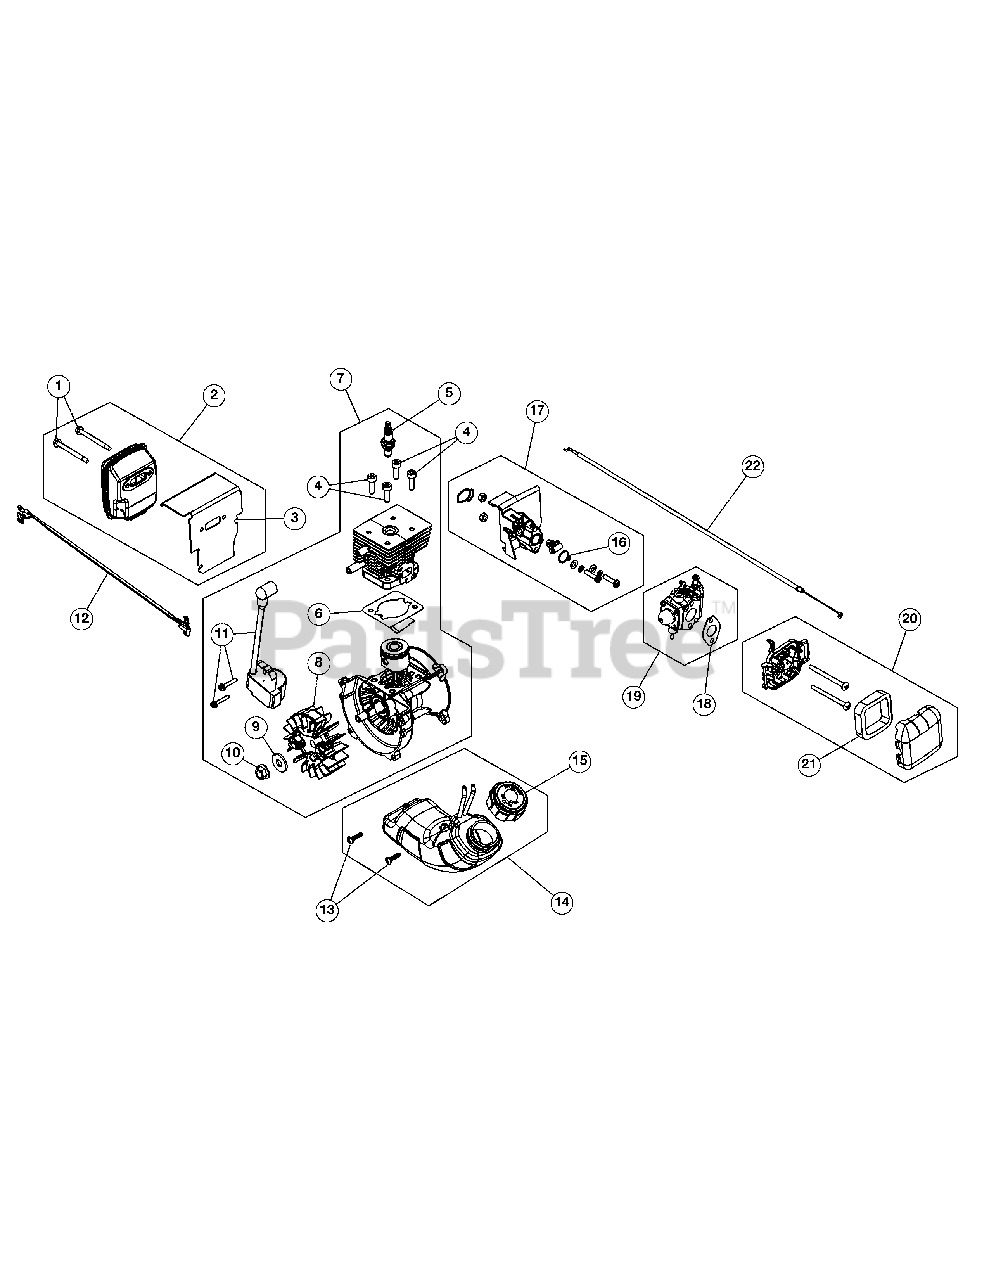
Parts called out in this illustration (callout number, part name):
1	Muffler Screws
2	Muffler Assembly (Incl. 1 & 3)
3	Muffler Gasket
5	Spark Plug
6	Cylinder Gasket
7	Shortblock Assembly (Incl. 4-6 & 8-11)
8	Flywheel Assembly
9	Washer
11	Module Assembly
12	Lead Wire
14	Fuel Tank Assembly (Incl. 13 & 15)
15	Fuel Cap
16	Insulator Gasket
17	Insulator Assembly (Incl. 16)
18	Carburetor Gasket
19	Carburetor Assembly (Incl. 18)
20	Aircleaner Assembly (Incl. 21)
21	Air Filter
22	Throttle Cable
